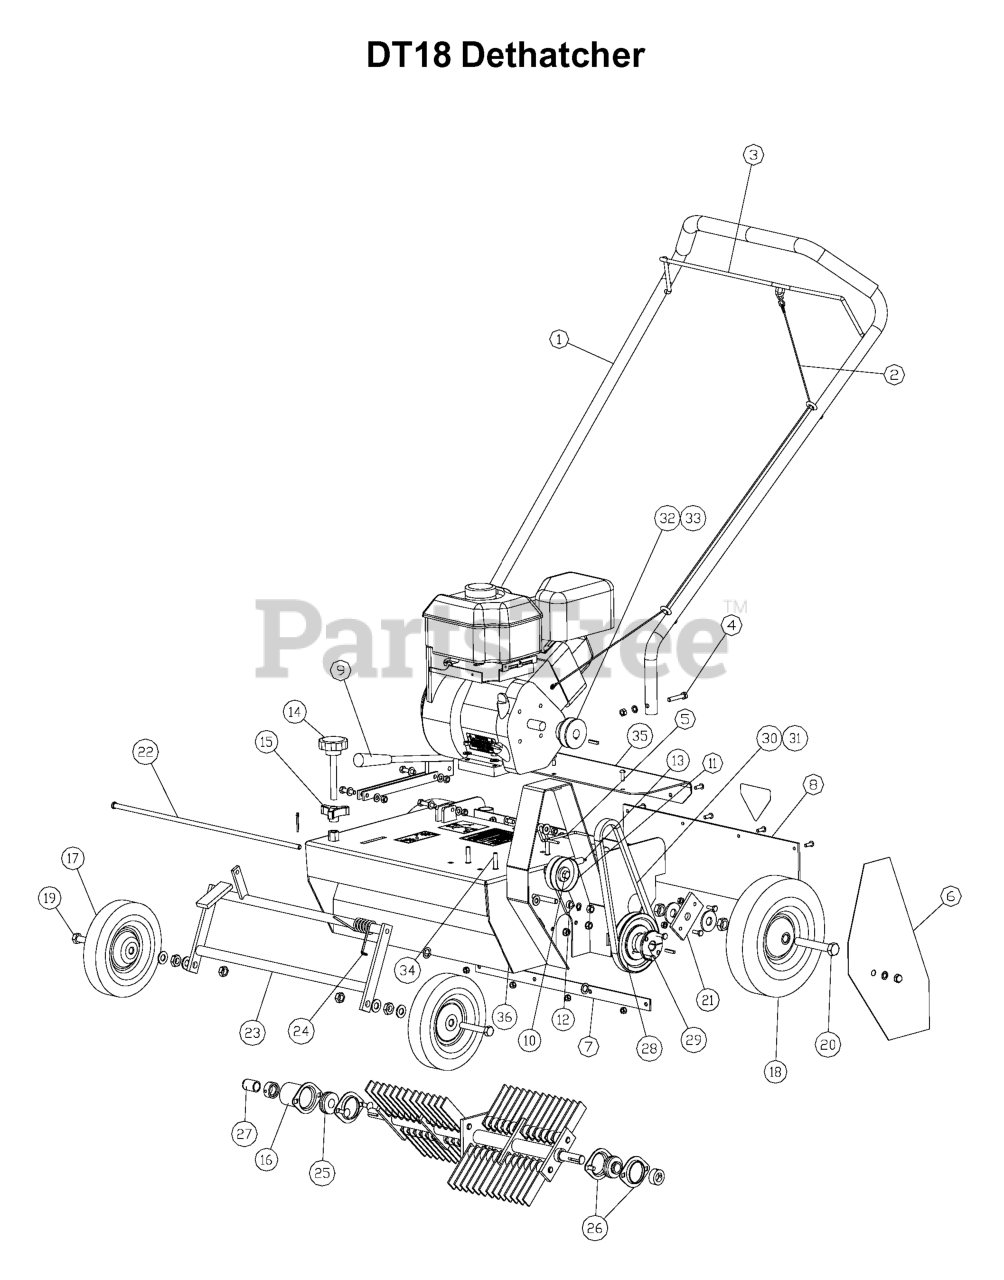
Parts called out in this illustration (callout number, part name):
1	KIT, HANDLE ASSY
2	CLUTCH CABLE
4	BOLT KIT
5	BELT KEEPER KIT
6	BELT GUARD KIT ORN
7	DEPTH LEVER ASSY
8	IDLER ASSY KIT
9	PULLEY
10	MTG ARM, IDLER PULLEY
11	SPRING
12	DEPTH ADJUSTMENT KNOB
13	3-PRONGED LOCK DEPTH
14	ROTOR GUARD
15	WHEEL
16	REAR WHEEL
17	BOLT KIT
18	BOLT KIT
19	WHEEL PLATE KIT
20	LIFT ARM ROD KIT
21	LIFT ARM ASSY OR
22	TORSION SPRING
23	BEARING
24	STAMPING KIT
25	ROTOR CAP
26	V-PULLEY
27	BUSHING KIT
28	V-BELT
29	V-BELT
30	V-PULLEY
31	V-PULLEY
32	ENGINE BOLT KIT
34	KIT BAGGER PLATFORM
35	NEOPRENE DEFLECTOR
37	CHUTE WELDMENT KIT
38	BAGGER FRAME
39	CATCHER BAG
40	Bagger conversion kit
